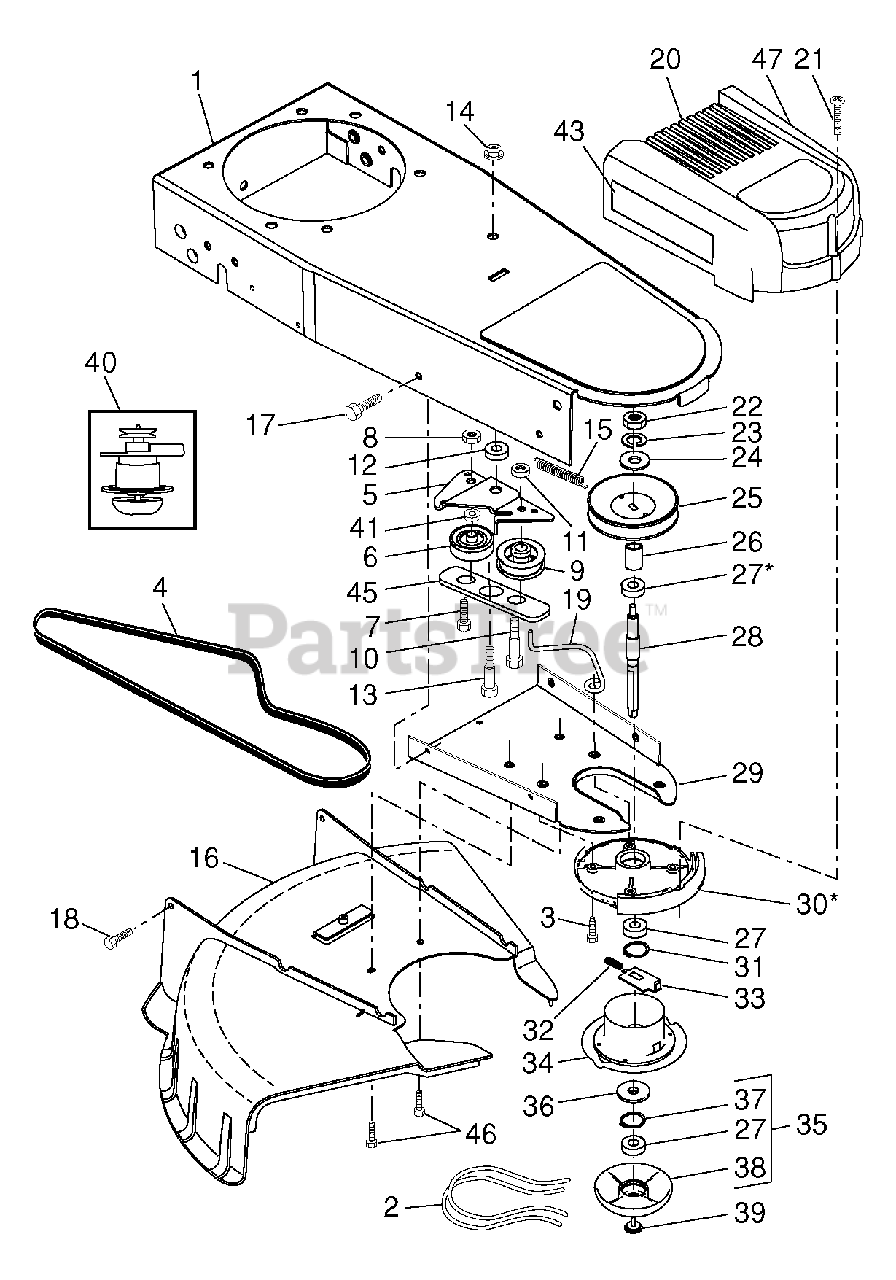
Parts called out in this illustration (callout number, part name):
1	HOUSING.CHASSIS ASM.MID.ORANGE
2	.155 Trimmer Line, 18.75 18-Pack
4	BELT-V.STRING TRIMMER.
5	RP.BRACKET.IDLER.TRIMMER.WHEEL
6	PULLEY.V-GROOVE.IDLER
7	BOLT, HEX HEAD 3/8-16 X 1.25
8	LOCKNUT
9	IDLER PULLEY
10	SHOULDER BOLT
11	NUT.CENTERLOCK.5/16-
12	SPACER.IDLER.BRACKET
13	BOLT SHOULDER 3/8 -16X1
14	NUT.HEX.FLANGE.3/8-16.LOCKNUT
15	SPRING.RETURN.WHEELED.TRIMMER
16	DEFLECTOR.BOTTOM.HW.TRIMMER
17	SCREW 14-20 X 5/8
19	KEEPER.BELT.STRING.TRIMMER
20	COVER.SUBASM.COVER/IMD.HUSQ
21	SCREW.SLOT.TORX.
22	NUT
23	LOCKWASHER
24	WASHER, FLAT 3/8
25	PULLEY.SPINDLE.WHEELED.TRIMMER
26	SPACER, PULLEY
27	BEARING
28	JACKSHAFT.WHEELED.TRIMMER
29	CHASSIS.COVER.BOTTOM.BLACK
30	SPINDLE HOUSING ASSEMBLY
31	RING, RETAINING, EXTERNAL,
32	SPRING.1.5".COMPRESSION
33	PLATE.LOCKING.WHEELED.TRIMMER
34	CARRIER PLATE ASSEMBLY
35	MOW BALL ASSEMBLY
36	COVER, BEARING
37	RING, RETAINING, INTERNAL,
38	MOW BALL
39	BOLT, MOW BALL
40	ASM.ADJUSTABLE.SPINDLE.WHLD.TR
41	SPACER (2 2MC)
43	DECAL.TRIMMER.WHEELED.HEIGHT
45	BRACKET.BELT.KEEPER.BLACK
47	DECAL.TRIMMER.WHEELED.INSTRUCT
